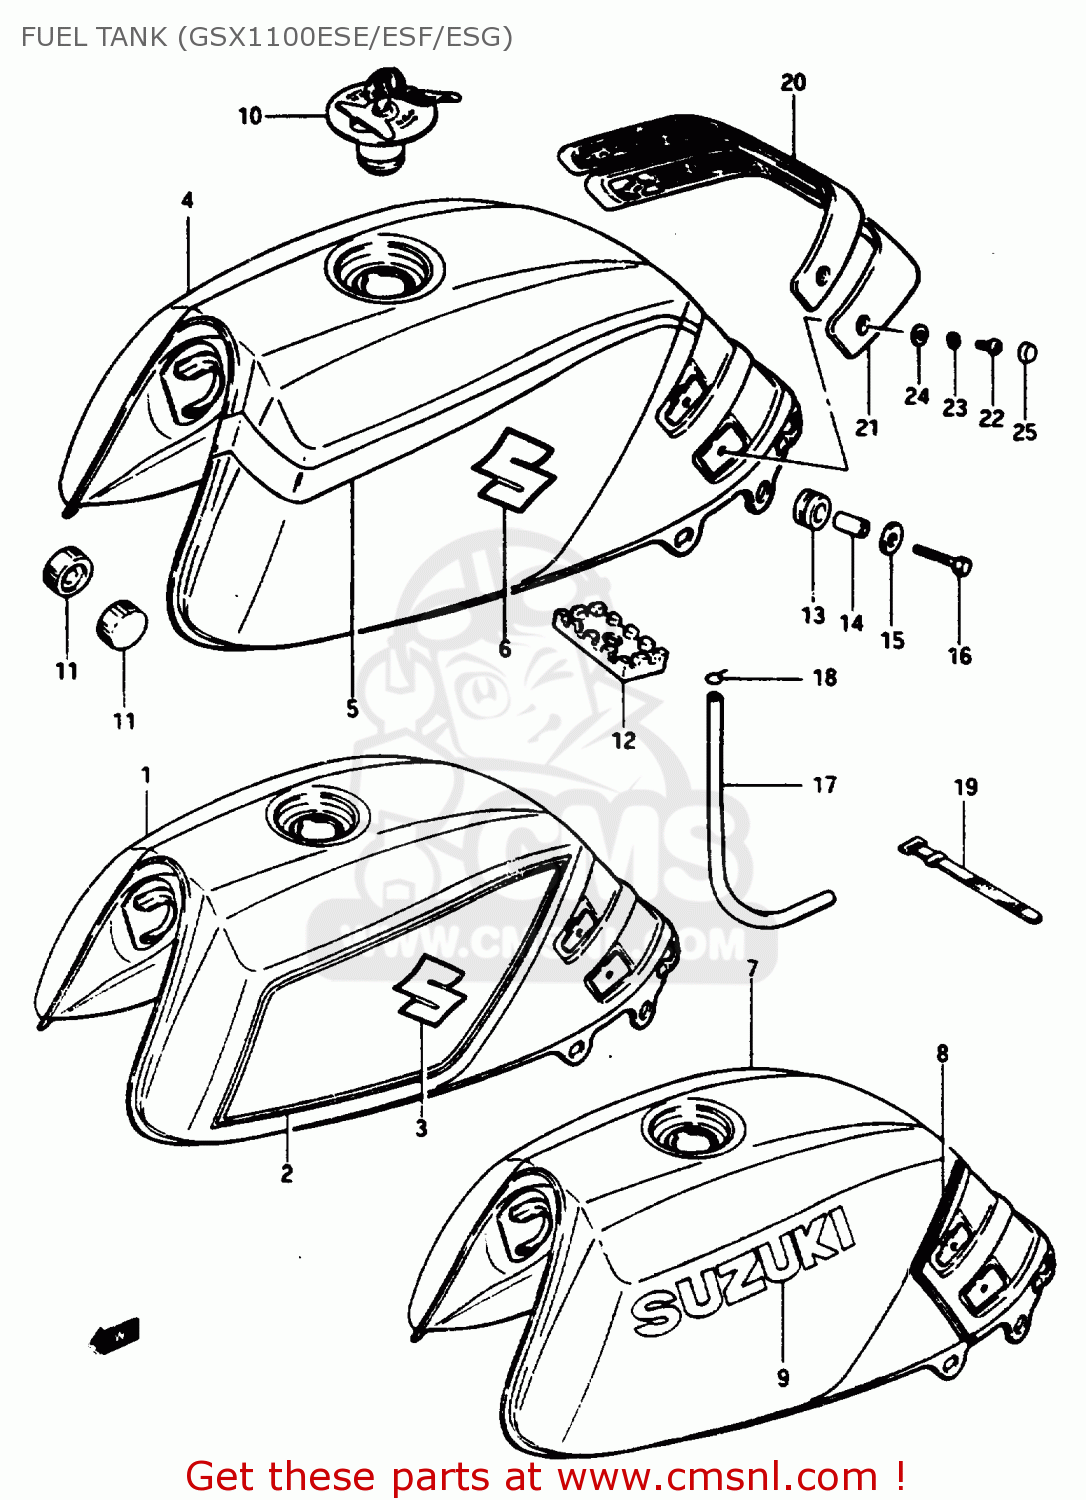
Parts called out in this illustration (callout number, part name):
1	TANK ASSY, FUEL
2	TAPE SET, FUEL TANK
3	EMBLEM
4	TANK ASSY, FUEL
5	TAPE SET,FUEL TANK
6	EMBLEM
7	TANK ASSY, FUEL
8	TAPE SET,FUEL TANK
9	EMBLEM
10	CAP ASSY,FUEL TANK
11	CUSHION
12	CUSHION,FUEL TANK CTR
13	CUSHION
14	SPACER (6.4X9X20)
15	WASHER (6.5X29X1.6)
16	BOLT 6X30
17	HOSE,FUEL
18	CLIP
19	CLAMP(L:187)
20	KNEE GRIP,FUEL TANK,UPPER
21	GRIP,FUEL TANK KNEE LWR
22	SCREW
23	LOCK WASHER
24	WASHER
25	CAP,KNEE GRIP
